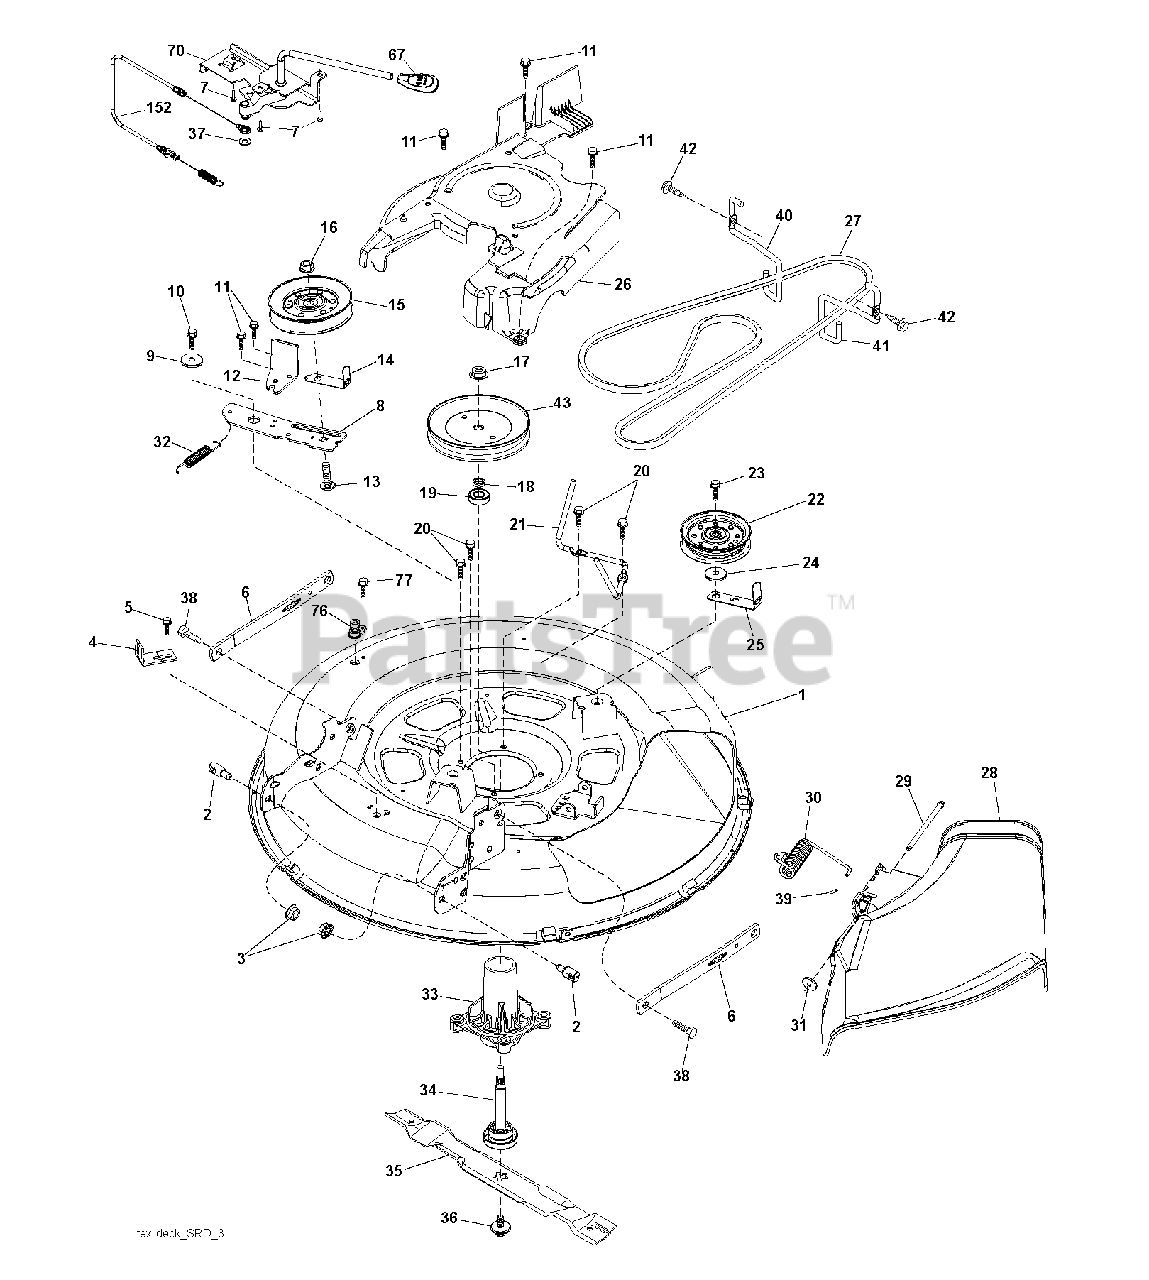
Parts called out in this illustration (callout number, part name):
2	STUD.FASTNER.W/D.ANTI-
3	NUT LOCK HEX FLANGE 5/16-18
7	SCREW.#10 X 0.750.BOS THREAD
9	SPACER.RETAINER
10	SCREW 3/8-16X1
11	SCREW 1/4-20X5/8
15	REPL BY 532 1467-63
17	NUT.FLANGE.LOCK.TOP
19	BEARING
20	SCREW, WASHER HEAD
22	FLAT IDLER PULLEY
24	WASHER
28	CHUTE, DISCHARGE 30
30	SPRING.TORSION.DEFLECT
31	NUT PUSH M
32	SPRING RETURN
33	HOUSING MANDREL
34	SHAFT.ASM.MDRL.N/GREASE.38
36	BOLT.WASHER.ASM.7/16-2
37	WASHER
38	BOLT.SHOULDER
39	CAP-SLEEVE LT
42	SCREW, 3/8-16X3/4
76	PORT.WASHOUT
77	SCREW 1/4-20X5/8
